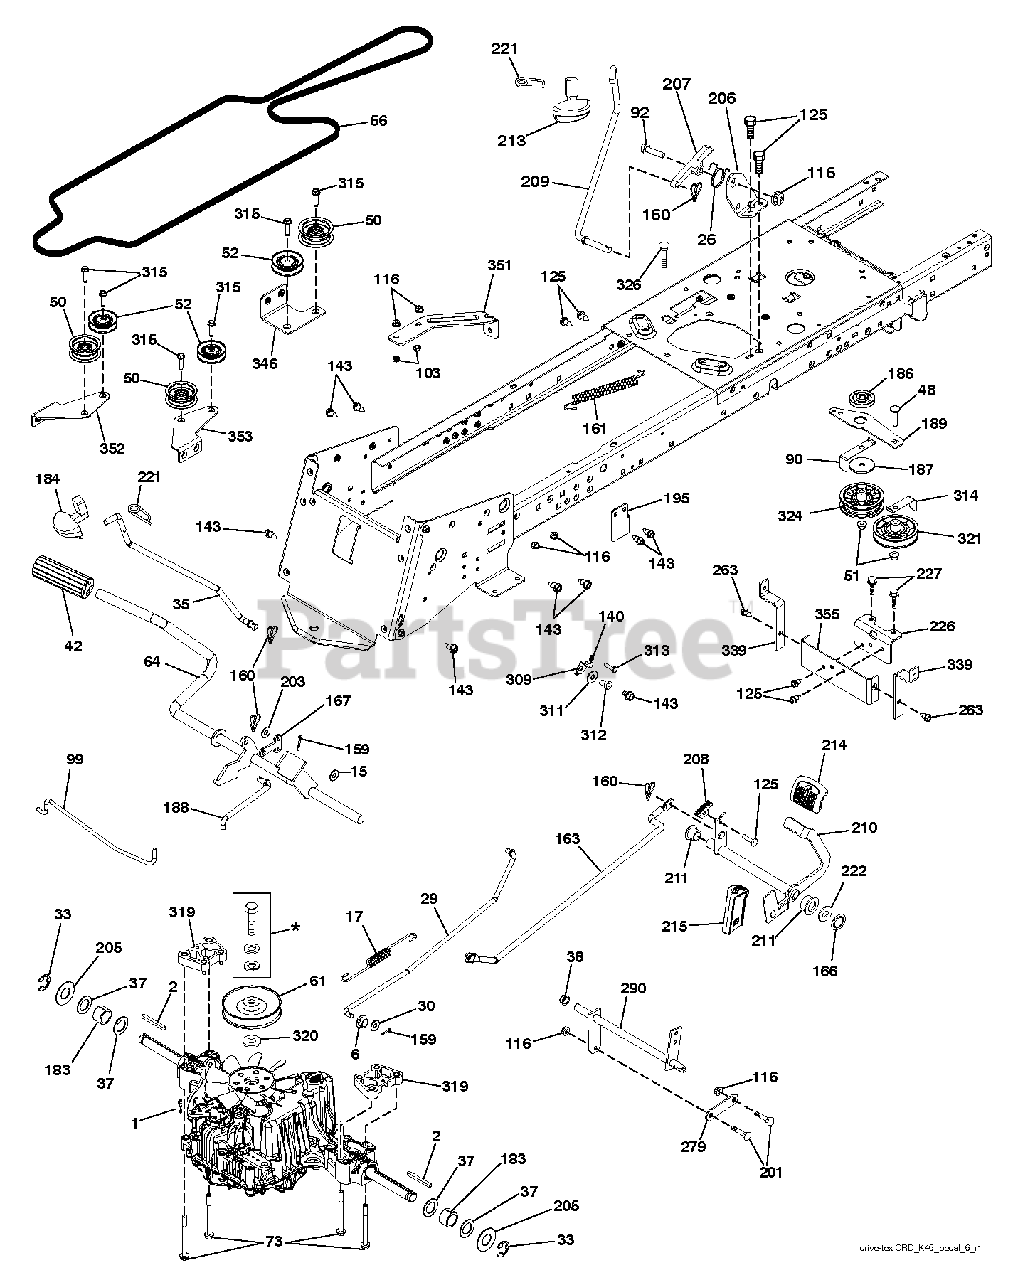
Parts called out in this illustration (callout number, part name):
2	SQUARE KEY
6	BUSHING.SNAP.NYL.BLK.
15	WASHER
17	SPRING
26	SPRING.RETURN.CRUISE
29	ROD
30	WASHER
35	ROD.BRAKE.PARTK.HUSQ.TEX
38	NYLINER SNAP 5/8" ID
42	PEDAL COVER T
48	BOLT.3/8-16X1.50
50	IDLER.FLAT.2.25.INCH
51	NUT LOCK FLG 3/8-16 UNC
52	PULLEY.V-IDLER.
56	V BELT DELV 113 K46 CRD
61	PULLEY
64	SHAFT.ASM.PEDAL.BRK.CNTR
73	BOLT.FLANGED
90	BRACKET KEEPER BELT CLUTCHING
92	BOLT
99	ROD
103	JAM NUT TI
116	NUT LOCK HEX FLANGE 5/16-18
125	SCREW
140	LOCKWASHER
143	SCREW LT
159	COTTER PIN
160	RETAINER CLIP
161	SPRING, RETURN LT
163	ROD
166	NUT.PUSH.625
167	LATCH.BRAKE.SPRING
183	SPACER AXLE
184	RB HANDLE.PARKG.BRK.HUS/PRED
186	SPACER.RETAINER
187	WASHER 12/32X2X10GA
188	RP LINK.CLUTCH.GROUND.DRIVE
189	BELLCRANK BELLCRANK GROUNDDRI
201	BOLT SHOULDER 5/16-18 UNC
203	WASHER
206	BRKT.MOUNT.LATCH.CRUIS
207	LATCH.CONTROL.CRUISE
208	GEAR.SECTOR.CONTROL.CR
209	ROD.CONTROL.CRUISE.GT.
210	ROCKER.ASM.PEDAL.CONTR
211	BEARING.NYLON
213	KNOB.CONTROL.CRUSIE.HU
214	PEDAL.FORWARD.PAD.TEX
215	PEDAL RUBBER REVERSE
221	RETAINER.SPRING.CLIP.H
222	WASHER 21/32 X 1-1/4 X 10 GA.
226	BRACKET.MOUNT.TORQUE.K46.TLT
227	SCREW
263	SCREW, 3/8-16X3/4
279	LINK
290	SHAFT SUBASM.SHAFT.CROSS.SHIFT
309	PLATE FASTENING LT
311	WASHER NYL
312	HUB.TAPERED.ROUND.CRD
314	RETAIN BELT
315	BOLT.5/16-18X1.25
319	SPACER SPACER TRANSAXLE TEX C
320	WASHER.SPACER.MANDREL
321	IDLER PULLEY
326	BOLT CARRIAGE
339	STRAP STRAP TORQUE K46 CRD TE
351	BRACKET BRACKET DECK SWAY
352	BRACKET BRACKET.IDLER
353	BRACKET
355	STRAP STRAP TORQUE K46 CRD TEX
